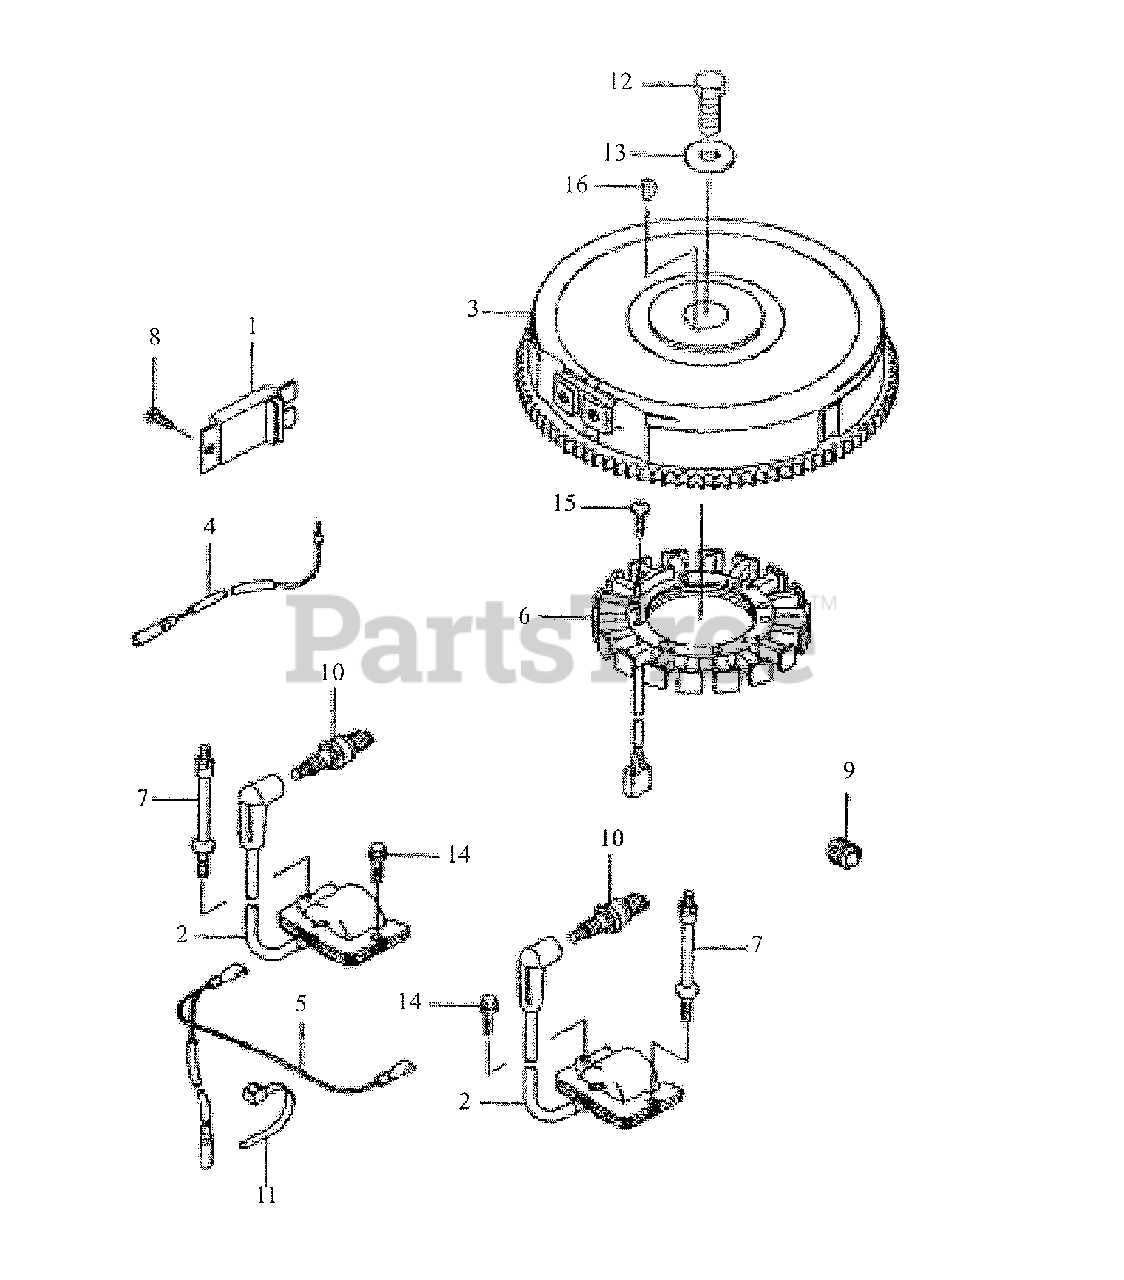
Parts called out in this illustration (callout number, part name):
1	Regulator-Voltage
2	Coil-Assy-Ignition
3	Flywheel-Assy
6	Coil-Charging
7	Stud
10	Spark Plug, NGK
12	Bolt, 12 x 30
14	Bolt-Flange
15	Screw
16	Key-Woodruff
